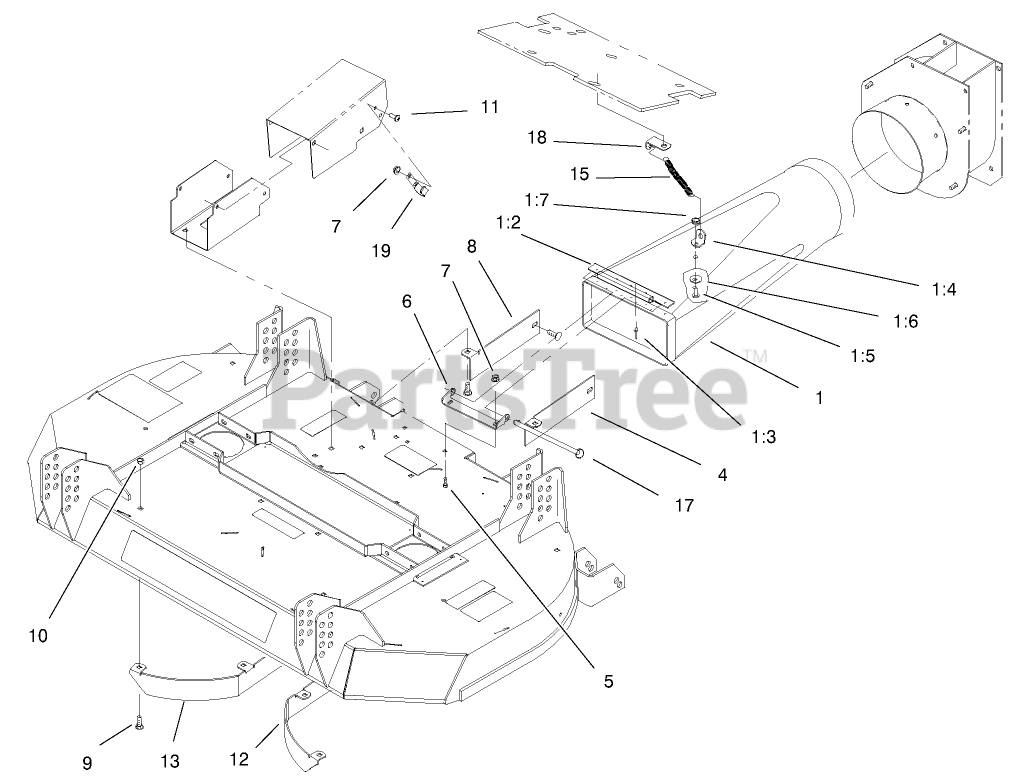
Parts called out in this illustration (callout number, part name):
1	ASM - PLENUM
1:2	BRACKET - PLENUM
1:3	RIVET-POP
1:4	BRACKET-SPRING
1:5	SCREW-PPH
1:6	WASHER-FLAT
1:7	NUT-HHF
4	Bracket-Discharge
5	SCREW-CARR
6	BRACKET - HINGE
7	NUT-HHF
8	Bracket-Discharge
9	SCREW-CARR
10	NUT-HF
11	SCREW-PPH
12	Baffle-LH
13	Baffle-RH
15	SPRING - EXTENSION
17	PIN - LOCKING
18	BRACKET - SPRING
19	CLIP - CABLE
